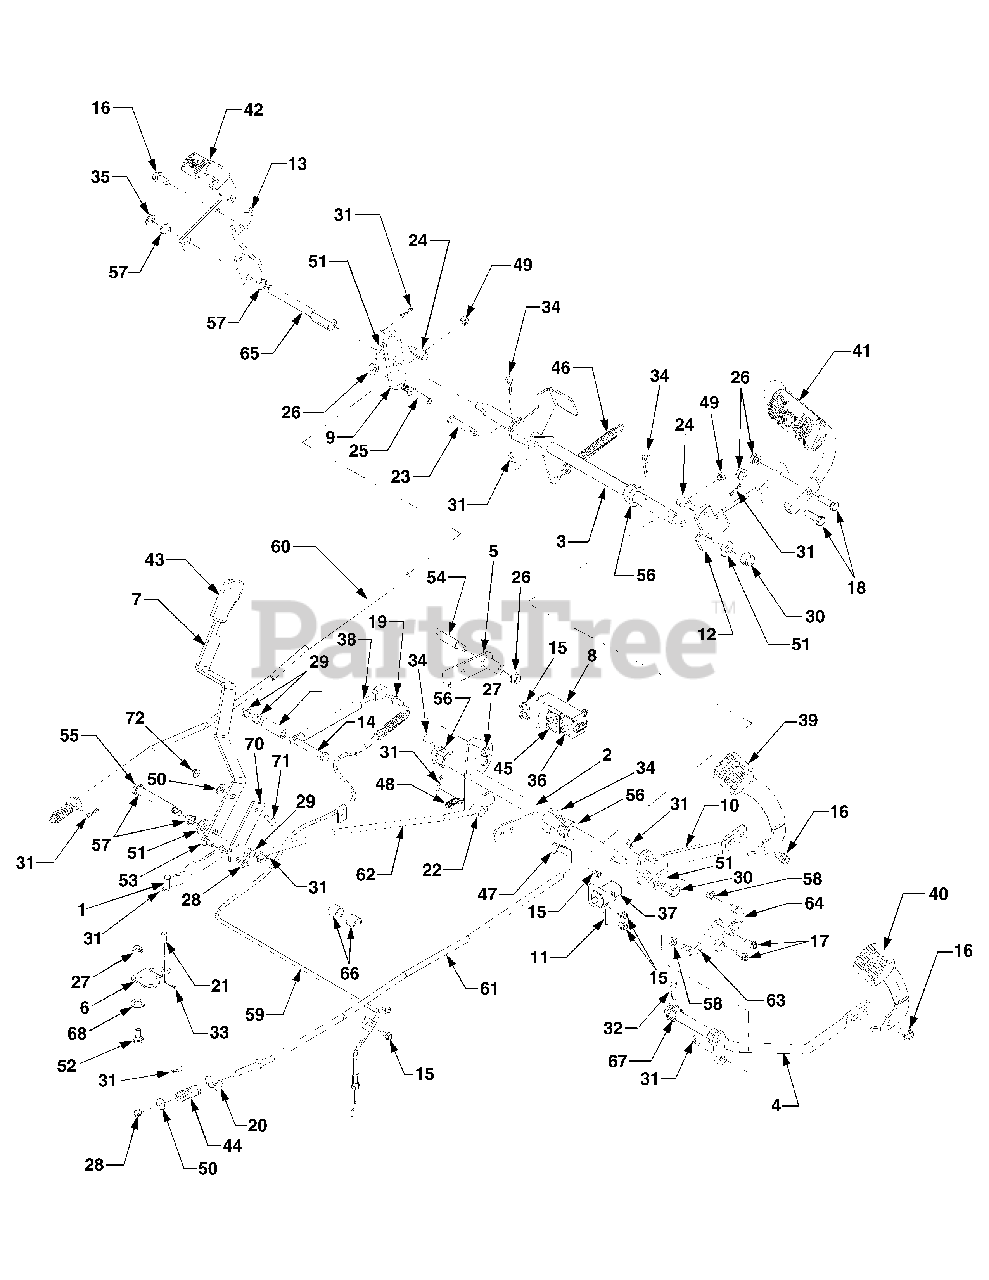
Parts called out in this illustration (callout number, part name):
1	Link, Hi-Lo
2	Shaft Assembly, Pedal
3	Shaft Assembly, Brake
4	Shaft Assembly, Reverse
5	Link Assembly, Parking Brake ..
6	Link, Hi-Lo Pivot
13	Bracket, Pedal Brace
14	Screw, Hex Cap 3/8-16 x 3.0 GR8
15	Screw, Hex Wash Hd Tapp 1/4-20 x .5
16	Screw, Hex Wash Hd Tapp 3/8-16 x .75
17	Screw, Hex Wash Hd Tapp 1/4-20 x .75
18	Screw, Hex Cap 3/8-16 x 1.25GR5
19	Stud, Cylinder, 5/16-18
20	Ferrule, Brake
21	Pin, Clevis, .25 x .5
22	Ferrule, 3/8-24 x .37
23	Pin, Clevis, 3/8 x 2.015
24	Ferrule, 3/8 - 24 x .375
25	Pin, 3/8-16: 3/8 x 2.43
26	Nut, Hex Flange Lock, 3/8-16 ...
27	Nut, Hex Flange Lock, 5/16-18
28	Nut, Hex Flange Lock, 1/4-20 ...
29	Nut, Hex Lock, 3/8-16
30	Nut, Hex Insert Lock, 1/2-20
31	Pin, Internal Cotter
32	Pin, Internal Cotter
33	Pin, Cotter, 3/32 x .750
34	Pin, Internal Cotter
35	E-Ring, .5 Dia
36	Switch, Plunger (Brake)
37	Switch, Plunger (Reverse)
38	Cylinder, Damper
39	Pedal, Forward
40	Pedal, Reverse
41	Pedal, Brake
42	Pedal, Diff. Lock
43	Grip, Handle
44	Spring, Compression
45	Switch, Plunger (Brake)
46	Spring, Extension, .62 x 6.12
47	Spring, Rev/No Cut
48	Spring, Extension, 3/8 x 1.44
49	Nut, Hex Jam, 3/8-24
50	Washer, Flat, .28 x .74 x .063 ...
51	Washer, Flat, .53 x .1.06 x .134
52	Screw, Shoulder, .435 x 1.78
53	Screw, Shoulder, ..375 x .181 ...
54	Screw, Shoulder, .498 x 1.635
55	Screw, Shoulder .498 x 3.245: 3/8-16
56	Bearing, Hex Flange, .752 ID
57	Bearing, Nylon. .50 ID x .341
58	Bearing, Flange, .375 x .58 x .25
59	Cable, Diff Lock
60	Rod, Brake, LH
61	Rod, Brake, RH
62	Rod, Hydro Control
63	Rod, Rear Connecting
64	Rod, Front Connecting
65	Shaft, Diff. Lock
66	Spacer, .508 x .75 x .68
67	Bearing, Hex Flange, .629 ID
68	Washer, Flat, .53 ID x .93 x .05..
69	Spacer, .39 x .625 x 1.74
71	Screw.Carriage, 1/4-20 x .75 GR5
72	Nut, Hex Flange Nylon Lock 14-20 GRF
